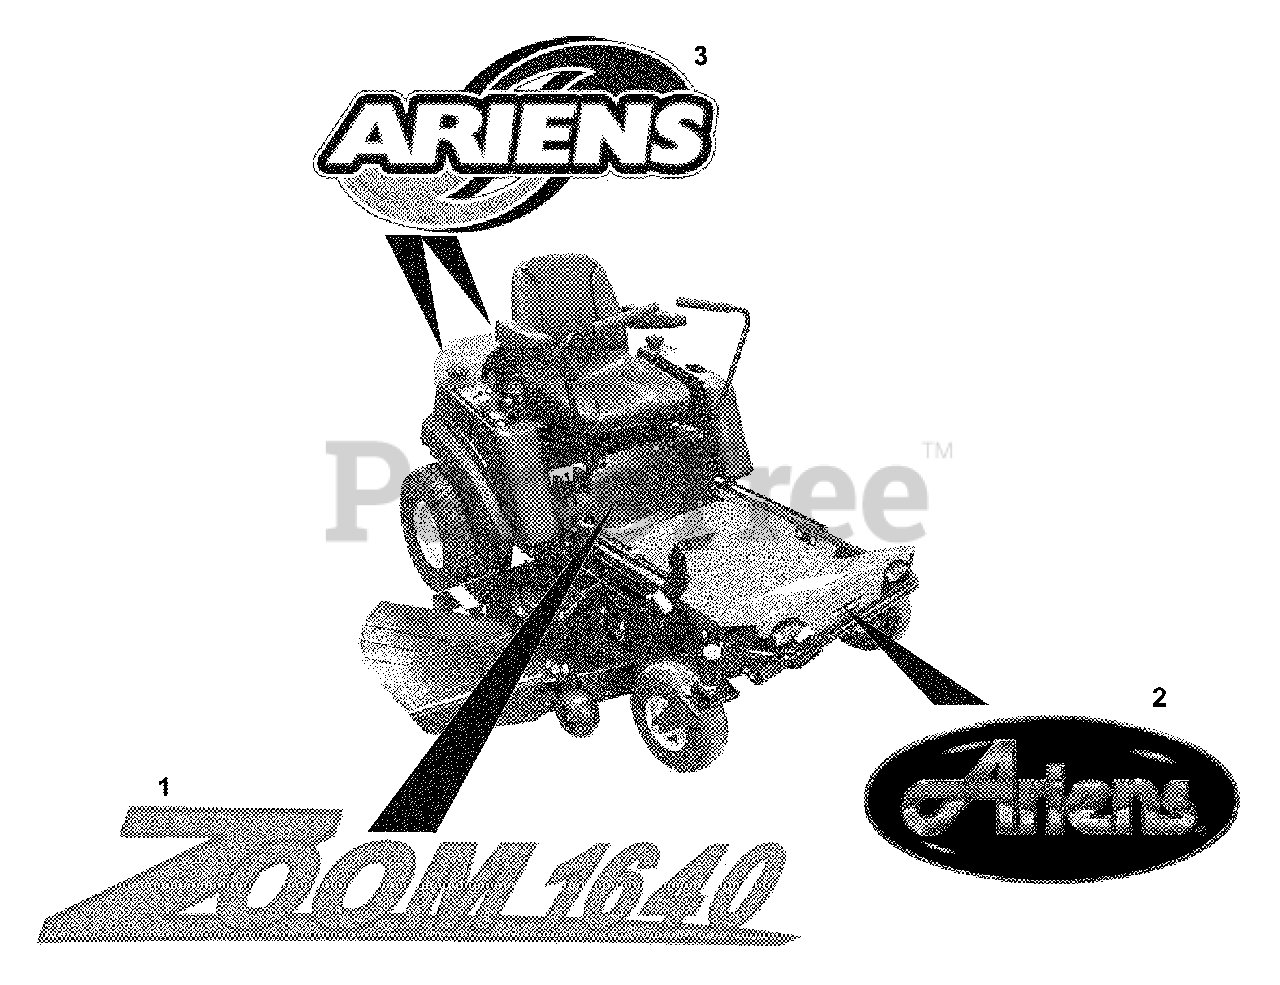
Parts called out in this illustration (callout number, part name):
1	DECAL ZOOM 1640
2	DECAL-ARIENS JEWEL
3	DECAL ZOOM HOOD
